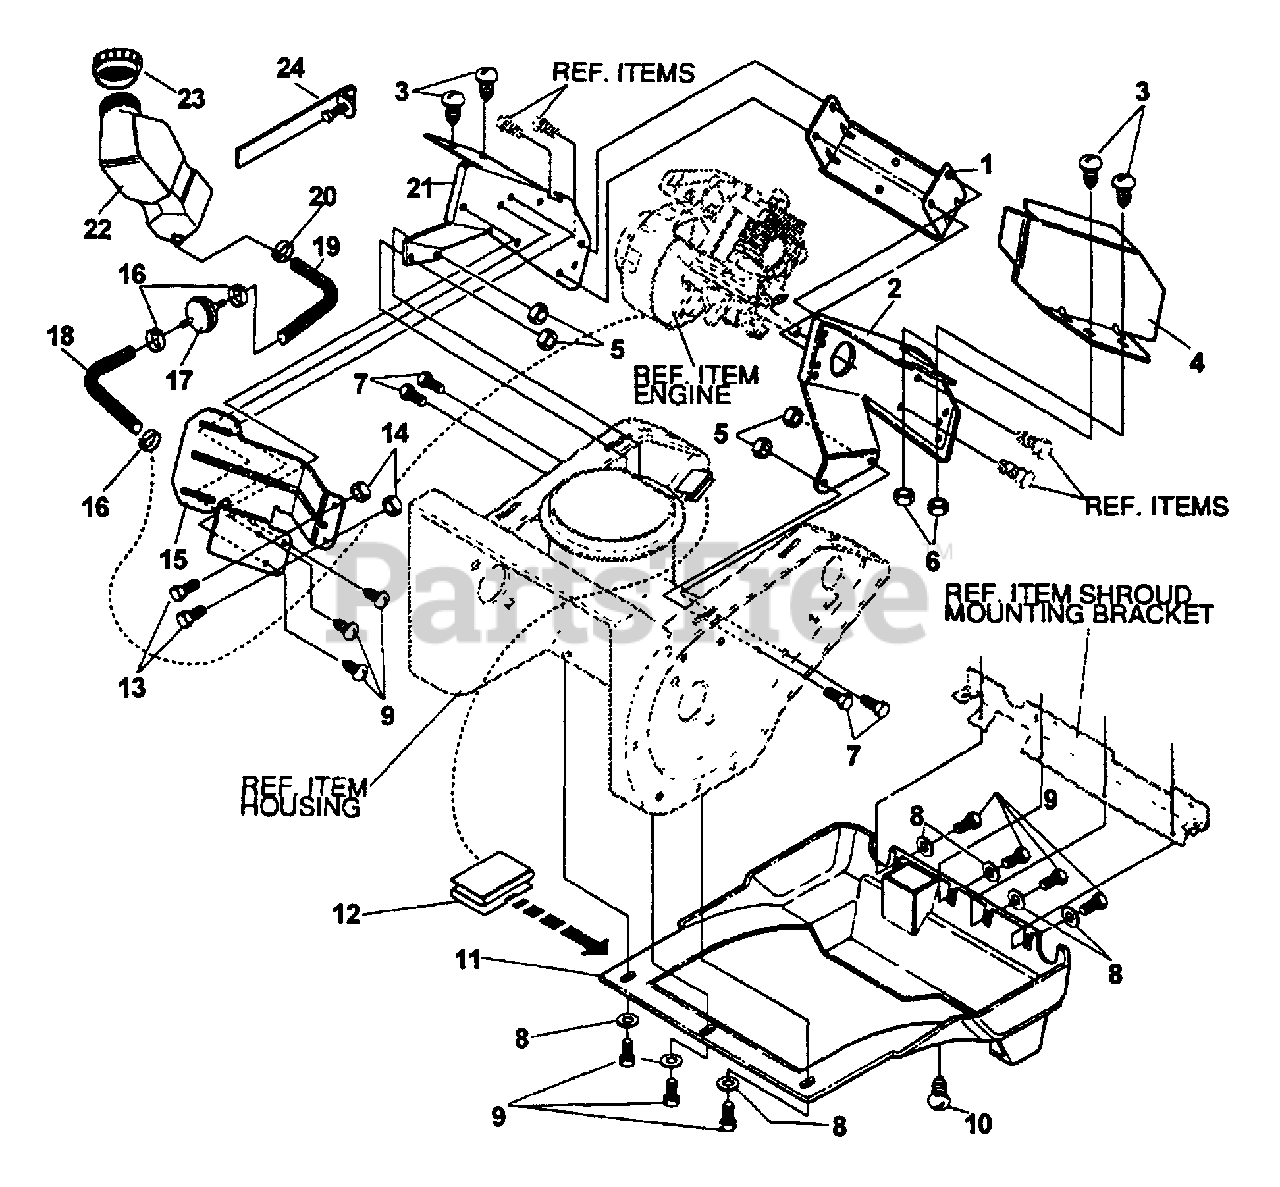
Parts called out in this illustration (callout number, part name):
1	SUPPORT, FRAME
2	PLATE, REAR MOUNT -- LEFT
3	SCREW - 1/4-20×0.63"
4	SHIELD, HEAT
5	NUT, 5/16"-18
6	NUT, 1/4"-20
7	SCREW - 5/16-18 X0.50" -- HEX HEAD CAP
8	WASHER
9	SCREW - 10-24×0.63" -- PAN HEAD
10	SCREW - 10-16×0.50"
11	SHROUD, BOTTOM
12	CLIP
13	SCREW - 10×24×0.50" -- HEX HEAD MACHINE
14	NUT
15	BRACKET, FUEL TANK
16	CLAMP, HOSE
17	FILTER
18	TUBING, GAS LINE 30"
19	TUBING, GAS LINE 8"
20	CLAMP, HOSE
21	PLATE, REAR MOUNT -- RIGHT
22	TANK, FUEL
23	CAP, FUEL
24	CLAMP, WORM DRIVE
